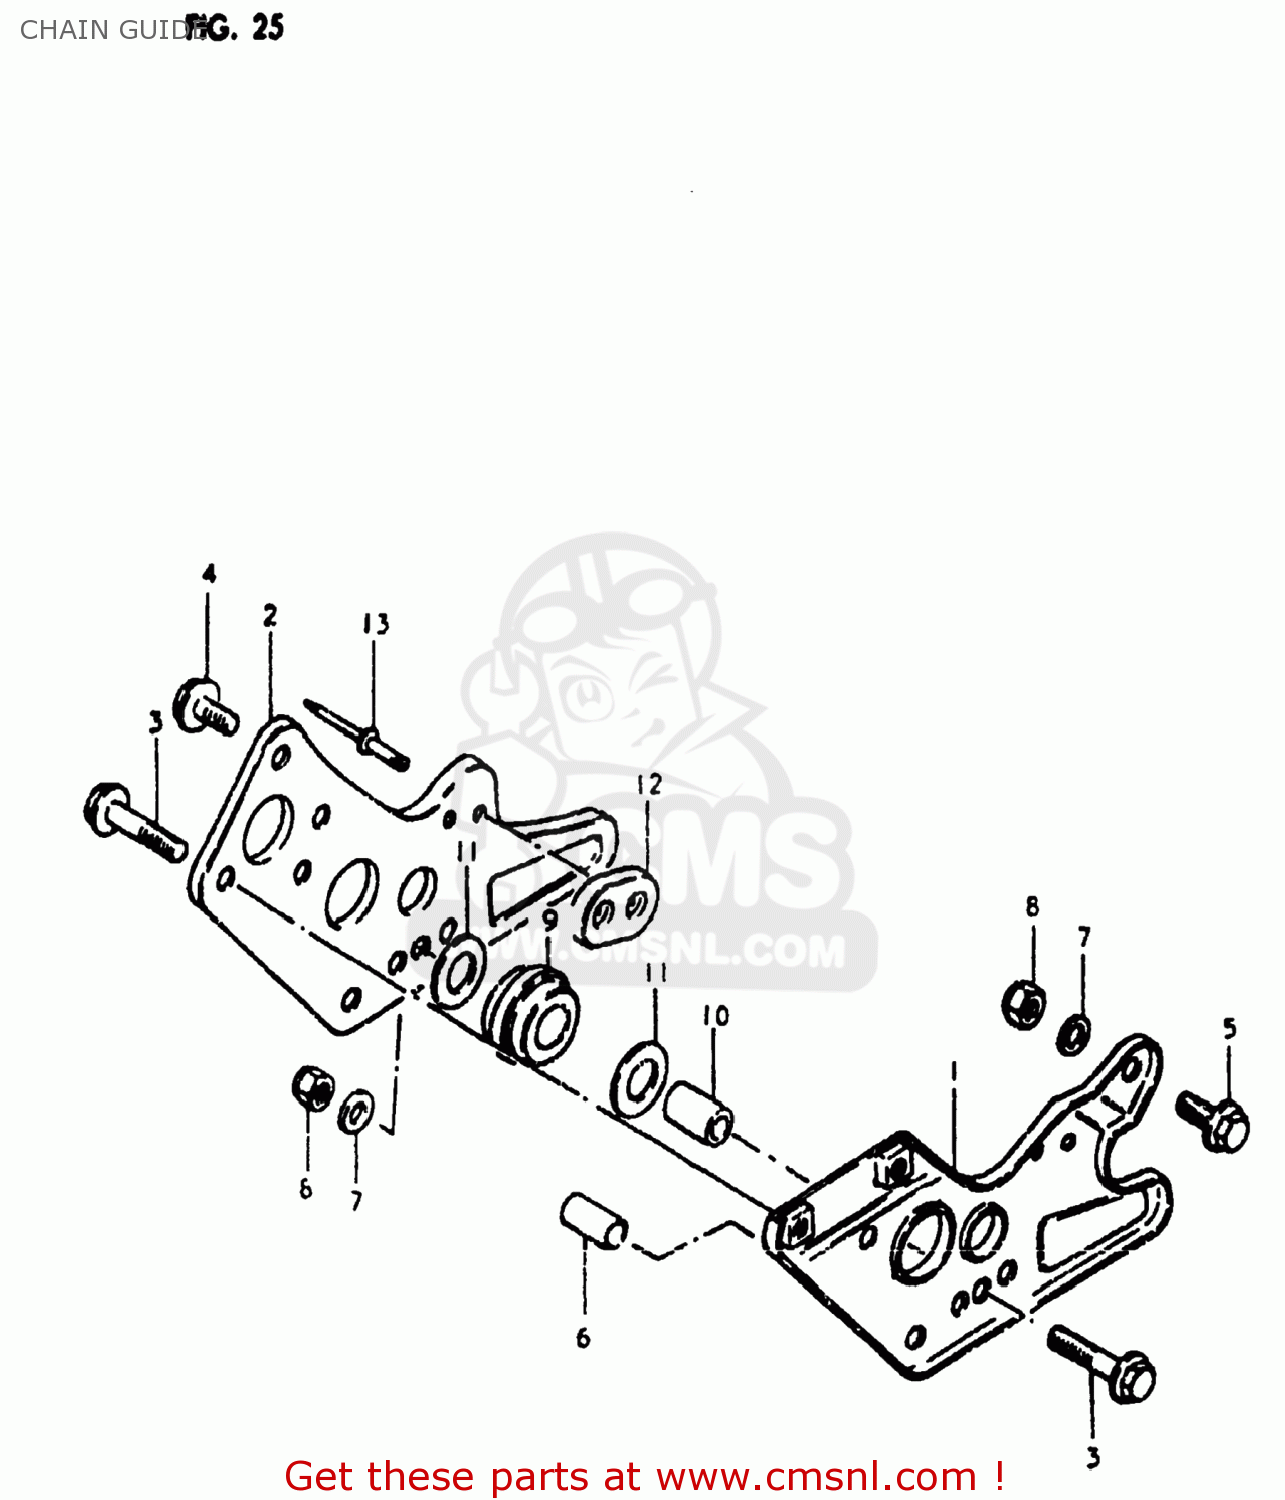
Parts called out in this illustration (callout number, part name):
1	PLATE,CHAIN GUIDE,OUTER
2	PLATE,CHAIN GUIDE,INNER
3	BOLT 6X35
4	BOLT
5	BOLT
6	SPACER(6.8X10X24.2)
7	WASHER
8	NUT 6MM
9	ROLLER,CHAIN GUIDE
10	SPACER,CHAIN GUIDE ROLLER
11	WASHER
12	PAD,DRIVE CHAIN GUIDE
13	RIVET
